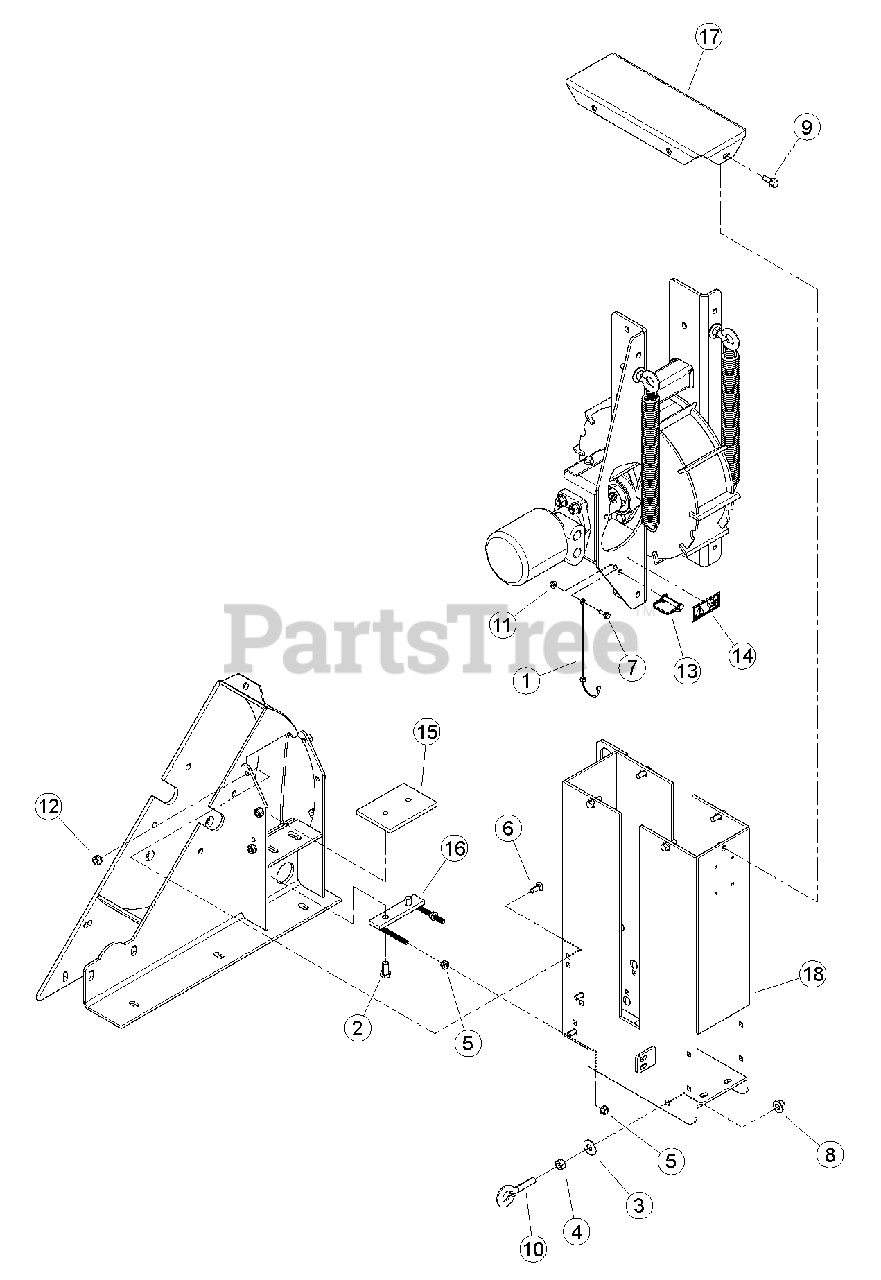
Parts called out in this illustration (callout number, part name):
1	LANYARD, NYLON
2	BOLT, 1/2 X 1 GR5 HEX CAPSCREW ZP
3	WASHER, 1/2" FLAT ZP
4	NUT, 1/2" HEX NC ZP
5	NUT, 3/8" SERRATED FLANGE NC ZP
6	BOLT, 3/8 X 1" GR5 CRG NC ZP
7	BOLT, 1/4-20 X 3/4 HWH GR5 CZP
8	NUT, 1/2-13 NYLOCK FLANGE
9	BOLT, 3/8 X 1 FLANGE NC
10	EYEBOLT, 1/2 X 2" ZP
11	NUT, 1/4-20 NYLOCK-FLANGE
12	NUT, 3/8-16 NYLOCK FLANGE
13	PIN, SNAP 3/8 X 1-1/2 USABLE LGH
14	DECAL, CRUSHING ISO
15	ANVIL, 4 INCH CHIPPER
16	WELDMENT, BLOCK ADJUSTOR
17	WELDMENT, TOP ROLLER COVER
18	WELDMENT, ROLLER SUPPORT 5 IN
